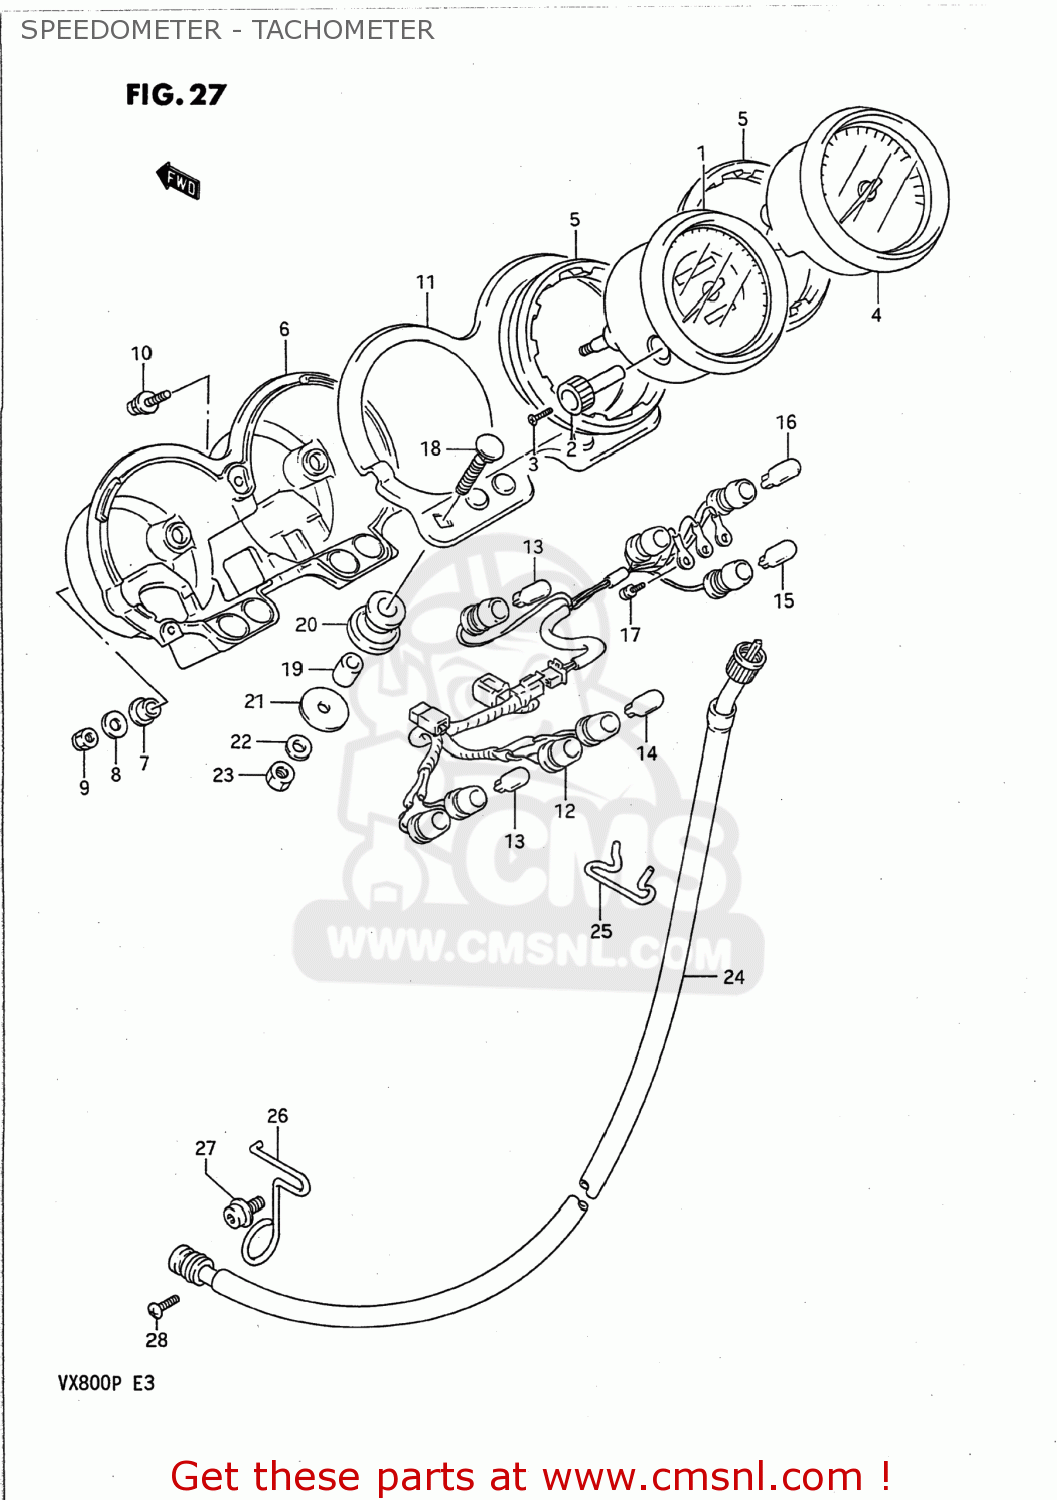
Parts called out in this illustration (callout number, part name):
1	SPEEDOMETER
2	KNOB
3	ROTOR,SPEED
4	TACHOMETER
5	DAMPER
6	COVER
7	CUSHION
8	WASHER
9	NUT
10	SCREW
11	BRACKET,METER
12	SOCKET & HARNESS ASSEMBLY
13	BULB(12V3.4W,T10)
14	BULB(12V1.7W,T10,WB121)
15	BULB(12V3W,T6.5)
16	BULB(12V1.7W,T6.5)
17	SCREW
18	BOLT(6X34)
19	SPACER (6.1X10X15.7)
20	CUSHION,METER BRACKET
21	WASHER (6.5X29X1.6)
22	WASHER,LOCK
23	NUT
24	CABLE ASSEMBLY,SPEEDOMETER
25	CLAMP,SPEEDOMETER CABLE
26	CLAMP,SPEEDOMETER CABLE
27	BOLT
28	SCREW
